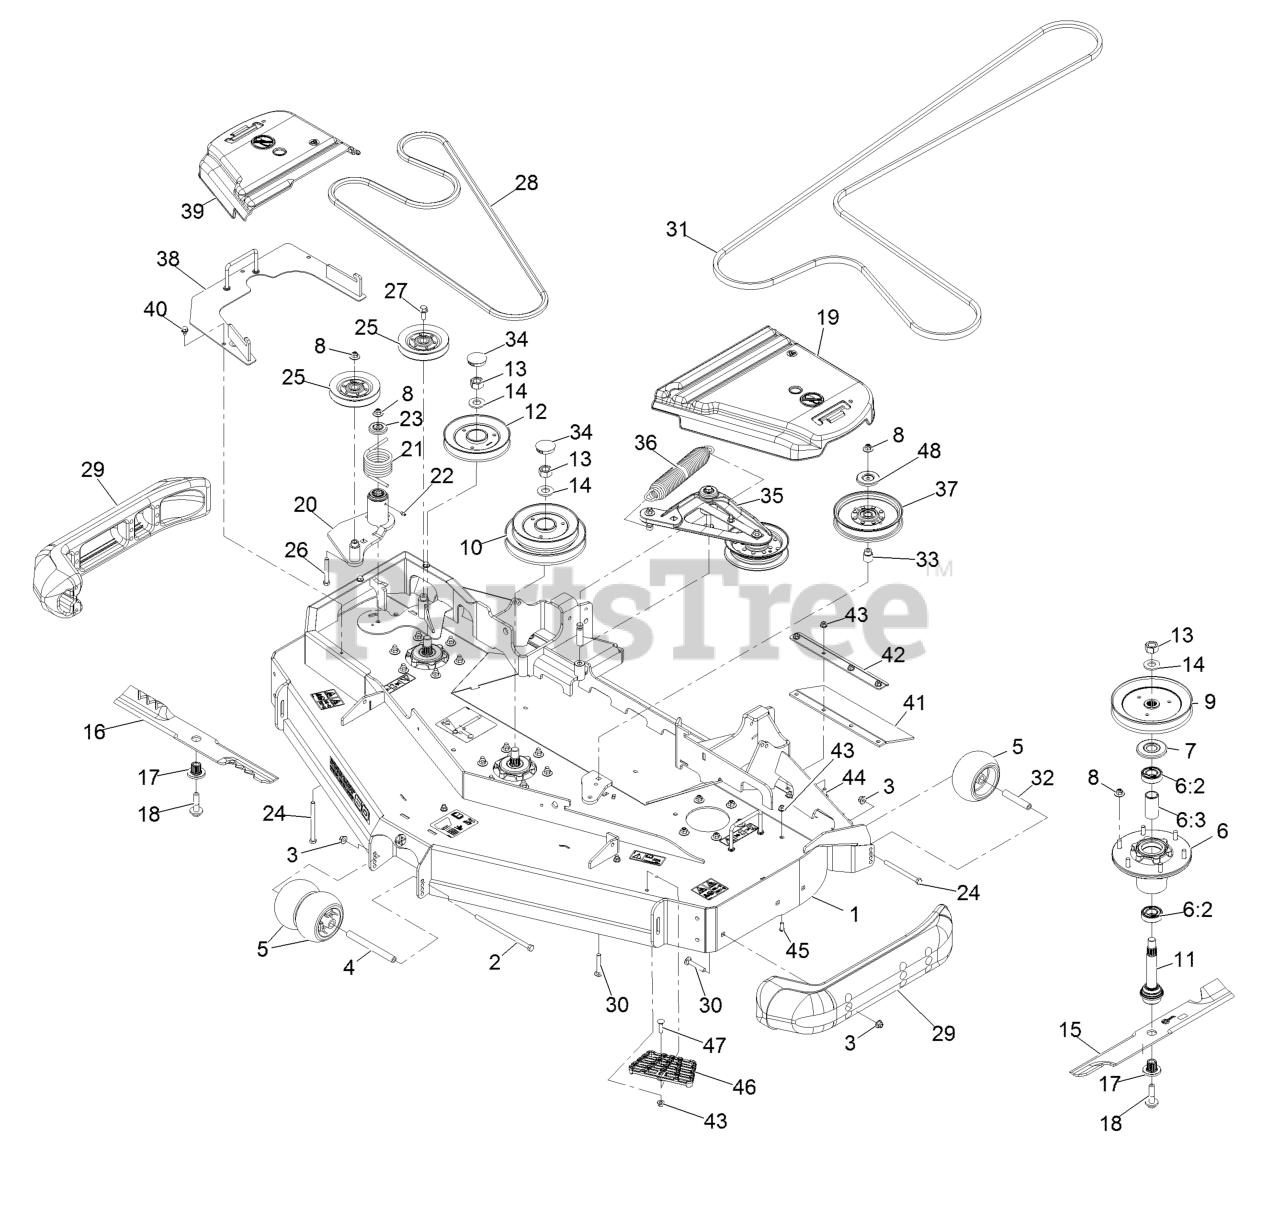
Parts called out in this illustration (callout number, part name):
1	Deck-Rd60 Nlz, W/Decals
2	Screw-HH 3/8-16 X 7 3/8
3	Nut-Nyloc 3/8-16 Flg
4	Spacer-Wheel
5	Roller-Scalp, Anti
6	ASM-Cutter Hsg With Bearings
6:2	Bearing-Ball
6:3	Spacer-Bearing
7	Guard,Bearing Top .989
8	Nut-Nyloc 3/8-16 Flg
9	Sheave,Blade Drive 7.25
10	Sheave, Double 60Rd
11	ASM-Spindle And Seal
12	Sheave-Rd Rev Drive Series 4
13	Nut-Hex
14	Washer-Spring Disc 3/4
15	Blade-Extreme 2, 20.50"
15	Blade, Notched
15	Blade, Low Lift
16	Blade-Low Lift 20.5, Rd60
16	Blade-Extreme 2-20.50, Rd60
17	Bushing, Splined
18	Screw-Sems 1/2-20 X 2.19
19	Cover-Belt, LH
20	Idler ASM
21	Spring-Torsion
22	Zerk-1/4-28 Str
23	Guard-Top
24	Screw-HH 3/8-16 X 4-1/2
26	Screw-HH 3/8-16 X 2 3/4
27	Screw-HH Flg 3/8-16 X 1
28	Belt
29	Skid-Bumper, Deck
30	Bolt-Carriage 3/8-16 X 2 1/
31	Belt
32	Tube-Spanner
33	Bushing, Idler
34	Plug,Black Nylon 1.75
35	Deck Idler ASM
36	Spring-Extension
37	Idler-Pulley, Flat 6.00X1.00
38	Cover-Drive Reverse
39	Cover-Belt, RH
40	Screw-HWH 5/16 X 1/2 Tf
41	Guard-Tire
42	Support-Outer Flap
43	Nut-Nyloc 5/16-18 Flg
44	Bolt-Carriage 5/16-18 X 7/8
45	Screw-Button Head 5/16-18 X 3/4
46	Step-Deck
47	Bolt-Carriage 5/16-18 X 1 1/4
48	Shield-Dust
